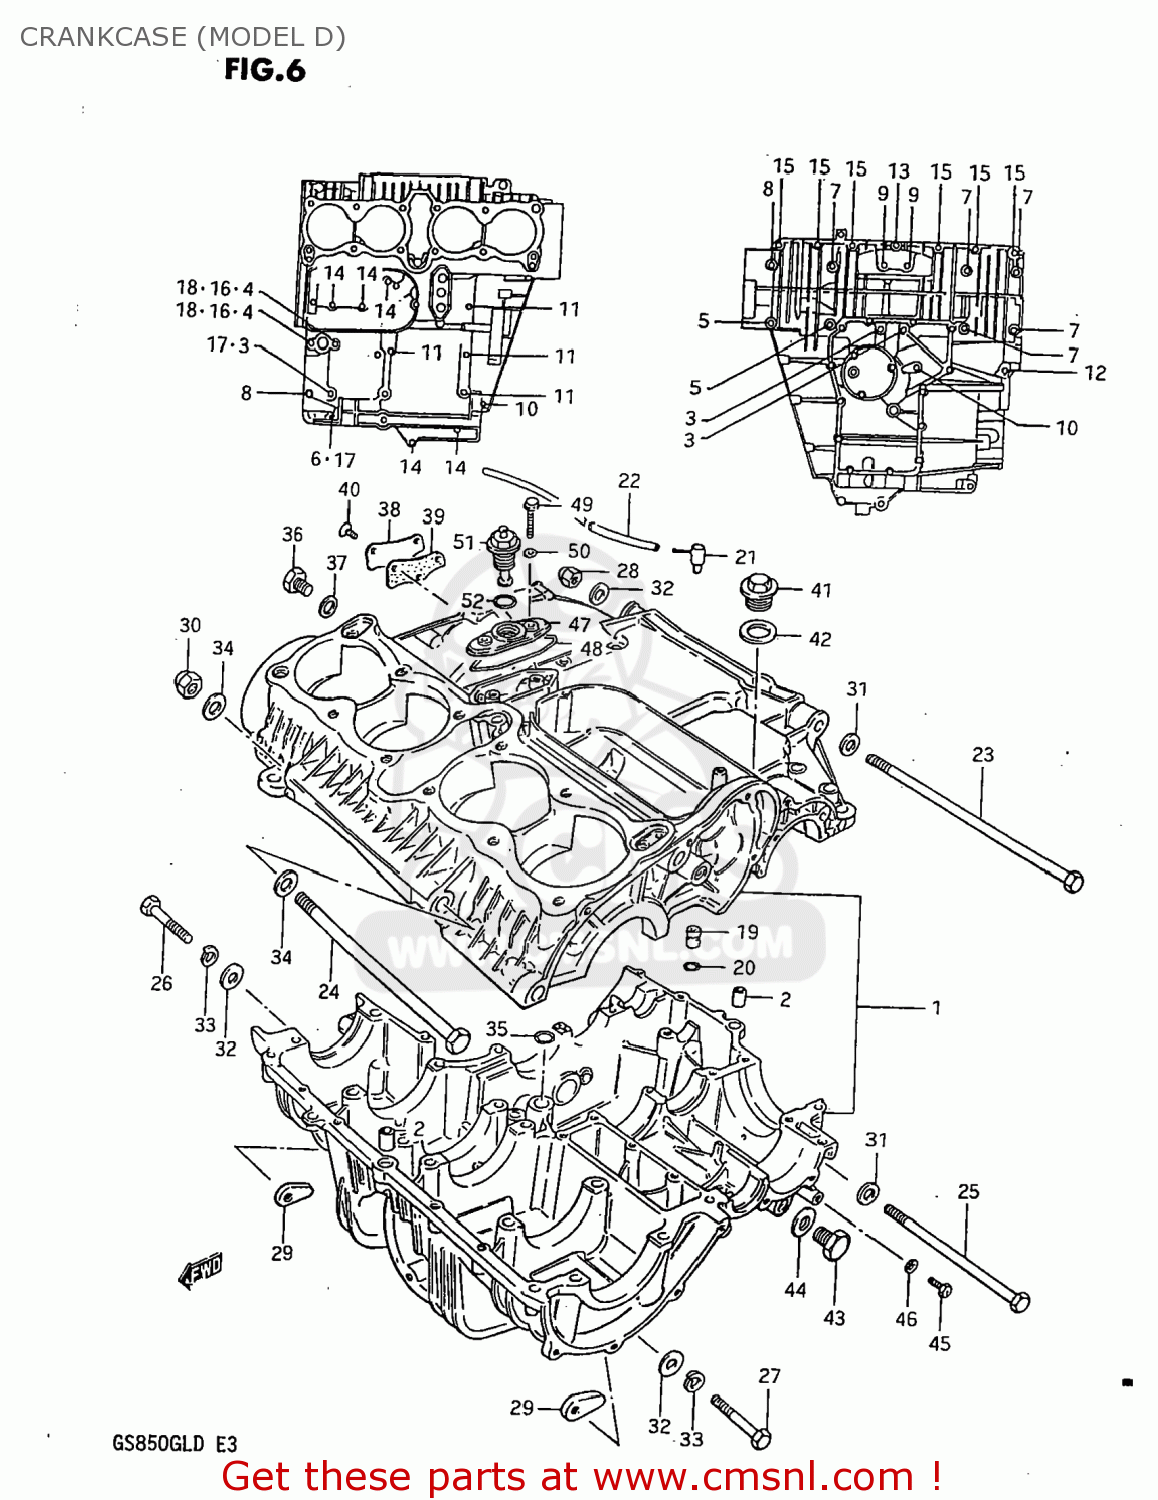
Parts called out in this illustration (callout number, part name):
1	CRANKCASE SET
2	PIN
3	BOLT
4	BOLT 8X110
5	BOLT
6	BOLT
7	BOLT (8X90)
8	BOLT (8X65)
9	BOLT 8X60
10	BOLT (6X90)
11	BOLT (6X75)
12	BOLT 6X55
13	BOLT 6X50
14	BOLT (6X45)
15	BOLT
16	NUT
17	NUT 8MM
18	GASKET 8.2X14X1 (NAS)
19	UNION
20	O RING(D:1.05,ID:3.1)
21	BPLUG,BEVEL GEAR BREATHER
22	HOSE
23	BOLT
24	SHAFT,REAR SWING ARM
25	BOLT
26	BOLT (10X60)
27	BOLT (10X50)
28	NUT (10MM)
29	NUT
30	NUT
31	WASHER (10.5X20X3.2)
32	WASHER
33	LOCK WASHER
34	WASHER
35	O RING(D:3.2,ID:12.9)
36	PLUG (14X12)
37	GASKET(14X19.2X2) (NAS)
38	CAP,OIL GALLERY
39	GASKET,OIL GALLERY (MCA)
40	SCREW
41	PLUG
42	GASKET
43	PLUG
44	GASKET(14X19.2X2) (NAS)
45	SCREW(6X10)
46	GASKET (NAS)
47	HOUSING,OIL PRESSURE SWITCH
48	O RING,PRESSURE SWITCH HOUSING
49	BOLT
50	GASKET (NAS)
51	SWITCH ASSEMBLY
52	O RING(D:1.9,ID:18.8)
